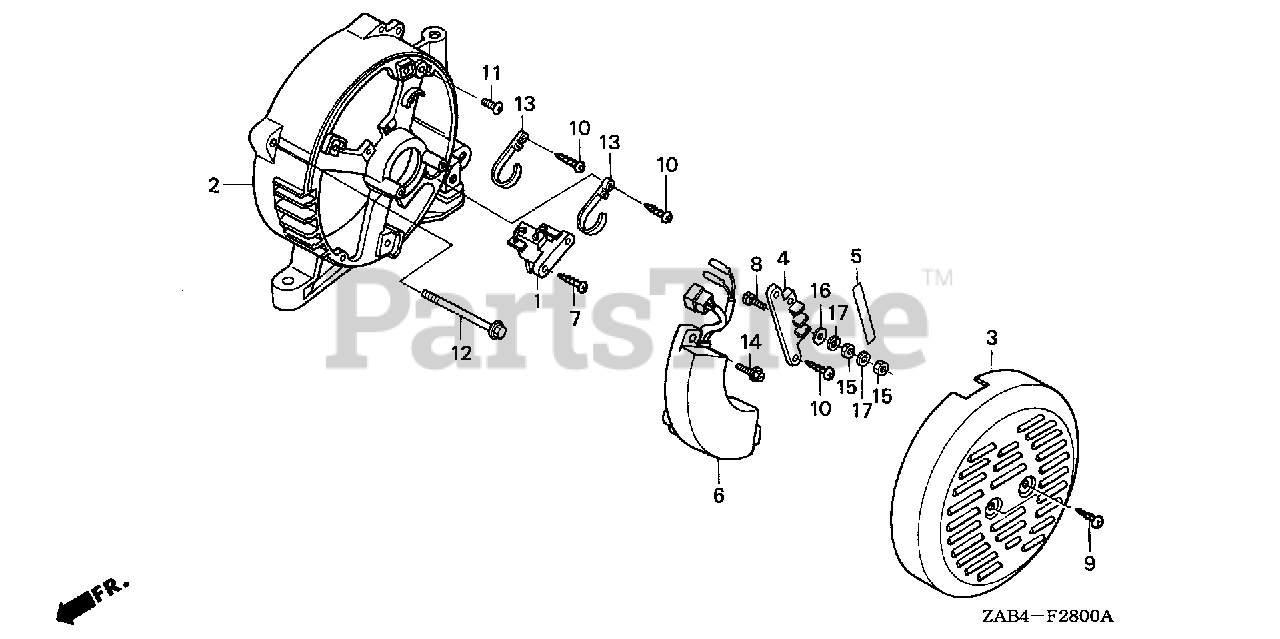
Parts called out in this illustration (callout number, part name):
1	BRUSH ASSY.
2	HOUSING, RR.
3	COVER, GENERATOR END *NH105* (MAT BLACK)
4	TERMINAL, VOLT CHANGE
5	MARK, VOLT
6	REGULATOR ASSY., AUTOMATIC VOLTAGE
7	SCREW, TAPPING (5X18)
8	BOLT, HEX. (5X20)
9	SCREW, TAPPING (5X12)
10	SCREW, TAPPING (5X14)
11	SCREW, PAN (5X12)
12	BOLT, FLANGE (6X175)
13	TIE, CABLE
14	SCREW, TAPPING (5X16)
15	NUT, HEX. (5MM)
16	WASHER, PLAIN (5MM)
17	WASHER, SPRING (5MM)
